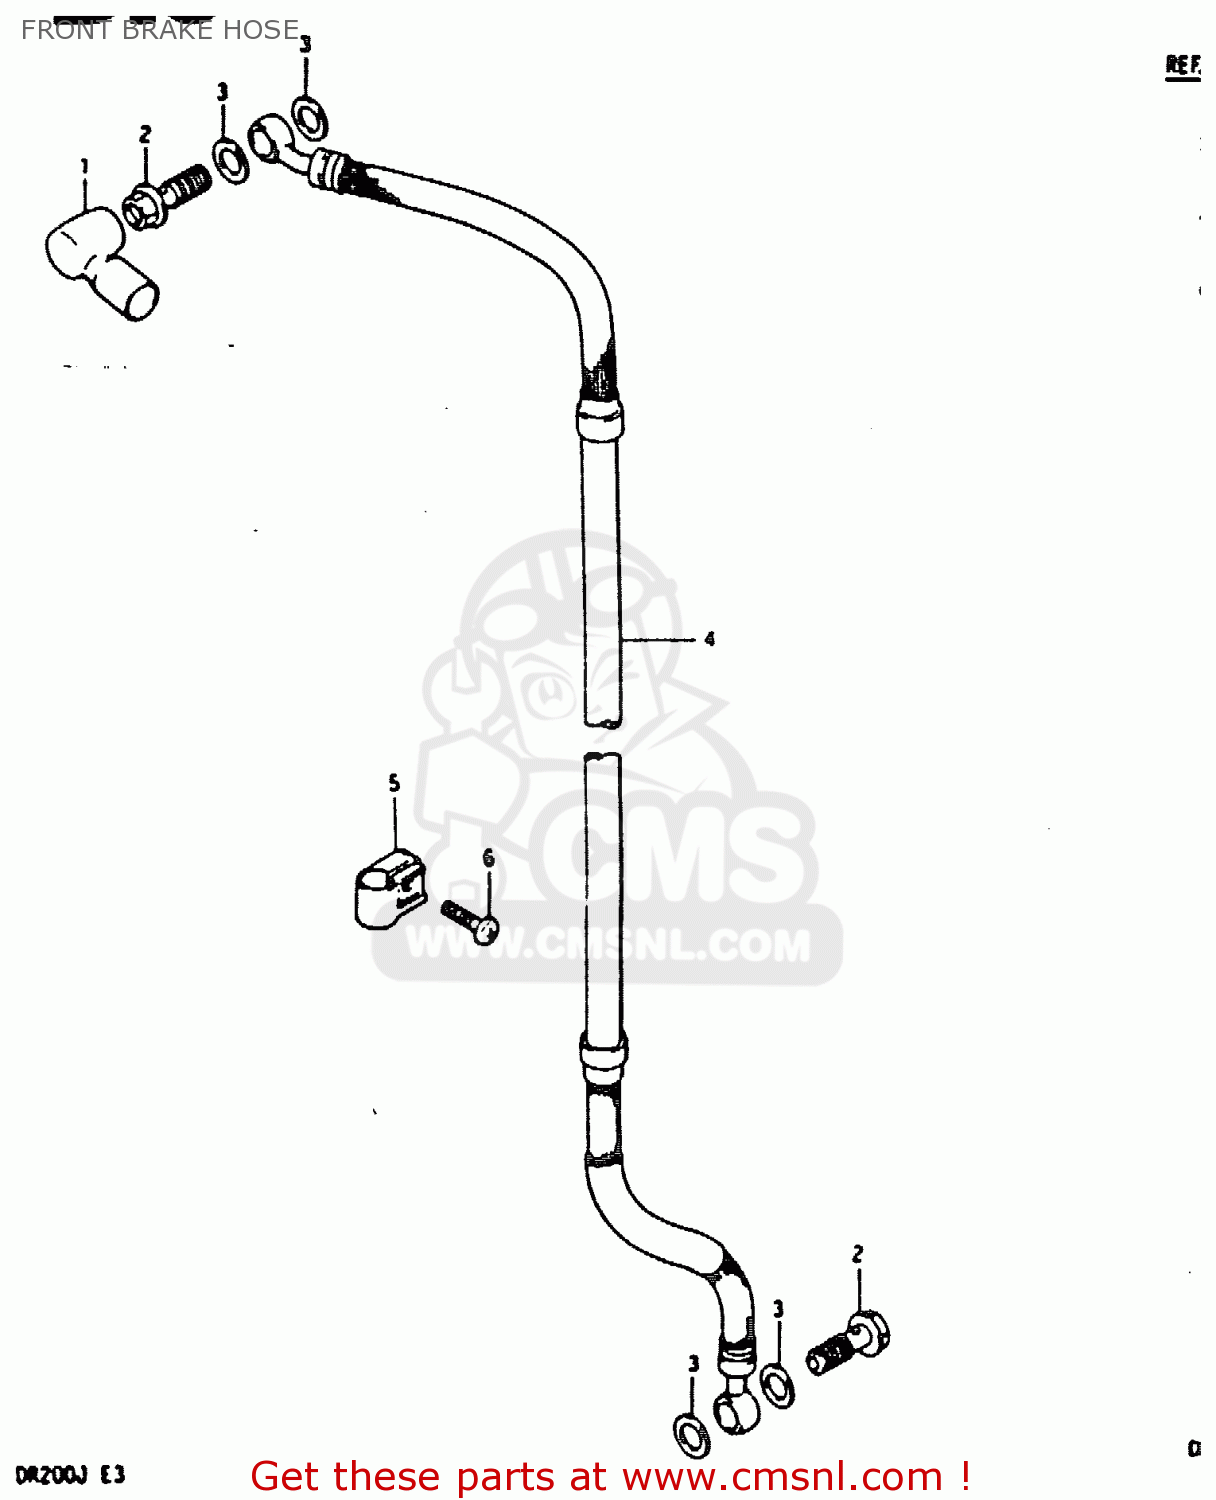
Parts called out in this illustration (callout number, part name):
1	BOOT,MASTER CYLINDER
2	BOLT UNION
3	WASHER(10X15X1.5)
4	HOSE,FRONT BRAKE
5	CLAMP,BRAKE HOSE
6	SCREW
